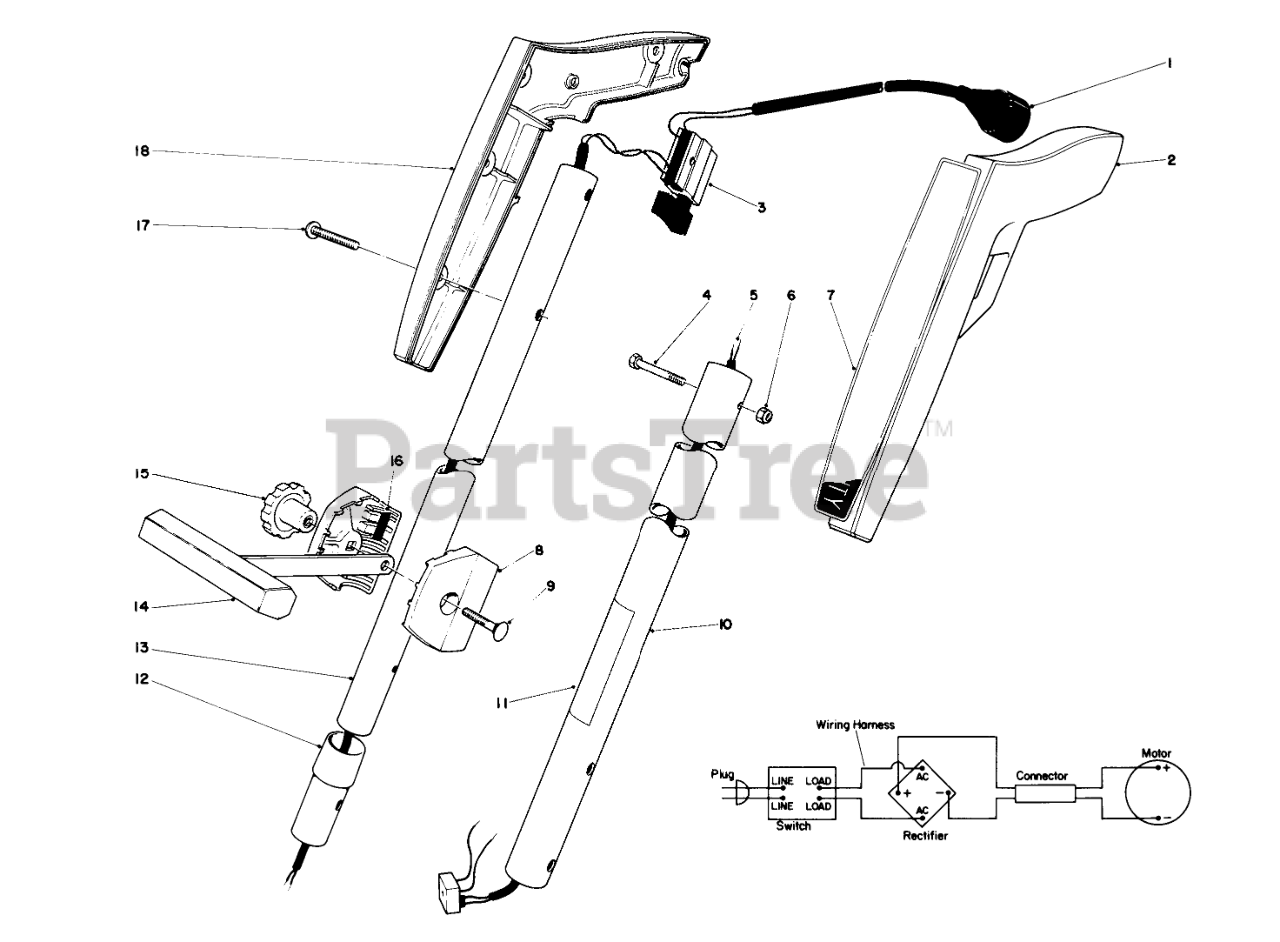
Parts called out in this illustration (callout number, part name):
1	Cord-Power
2	Left Hand Grip
3	SWITCH SINGLE SPEED
4	Screw
5	WIRE HARNESS
6	NUT-LOCK, NI
7	Decal
8	Bracket
9	Carriage Bolt
10	Lower Tube
11	REP. SERIAL PLT
12	Tubing Sleeve
13	Tube-Upper
14	Tee Handle
16	RUBBER INSERT
18	Right Hand Grip
